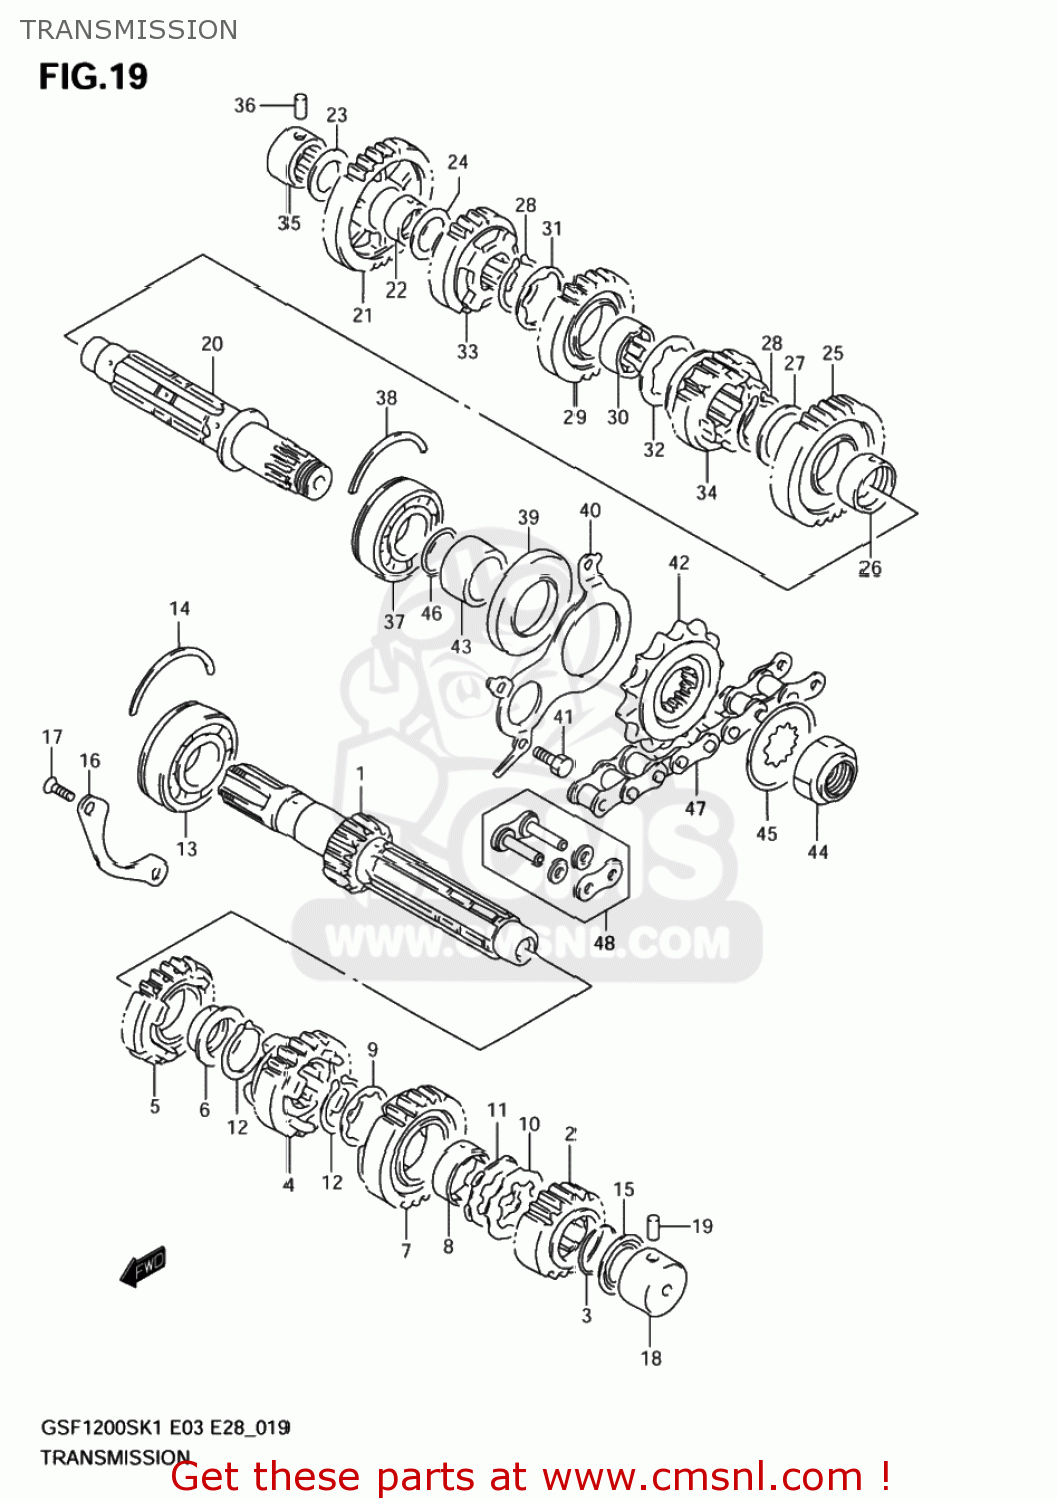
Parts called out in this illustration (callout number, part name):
1	SHAFT,COUNTER(NT:13)
2	GEAR,2ND DRIVE(NT:19)
3	CIRCLIP
4	GEAR,3RD DRIVE
5	GEAR,FOURTH DRIVE (NT:22)
6	BUSHING
7	GEAR,FIFTH DRIVE (NT:23)
8	BUSH,5TH DRIVE GEAR
9	WASHER,LOCK
10	WASHER,LOCK
11	WASHER
12	RING,SNAP
13	BEARING(25X62X17)
14	C RING
15	SEAL,OIL(20X31.2X2.7)
16	RETAINER,CNTR SHAFT BEARING
17	SCREW(6X12)
18	BEARING(20X34X17.5)
19	PIN
20	SHAFT,DRIVE
21	GEAR,1ST DRIVEN(NT:31)
22	BUSH
23	SHIM(20X34X1)
24	SHIM(22X34X1)
25	GEAR,2ND DRIVEN(NT:31)
26	BUSH(28X32X11)
27	SHIM(28X36X1)
28	CIRCLIP
29	GEAR,THIRD DRIVEN (NT:25)
30	BUSH,3RD DRIVEN GEAR
31	WASHER,LOCK
32	WASHER,LOCK
33	GEAR,FOURTH DRIVEN (NT:23)
34	GEAR,5TH DRIVEN(NT:21)
35	BEARING(20X34X20)
36	PIN
37	BEARING(25X62X21.6)
38	C RING
39	SEAL,OIL(34X62X6)
40	RETAINER,DRIVE SHAFT OIL SEAL
41	BOLT
42	SPROCKET,ENGINE(NT:15)
43	SPACER(25X34X19)
44	NUT
45	WASHER,LOCK
46	O RING(D:1,ID:24.5)
47	CHAIN ASSEMBLY RK GB50GSVZ
48	JOINT SET,DRIVE CHAIN
